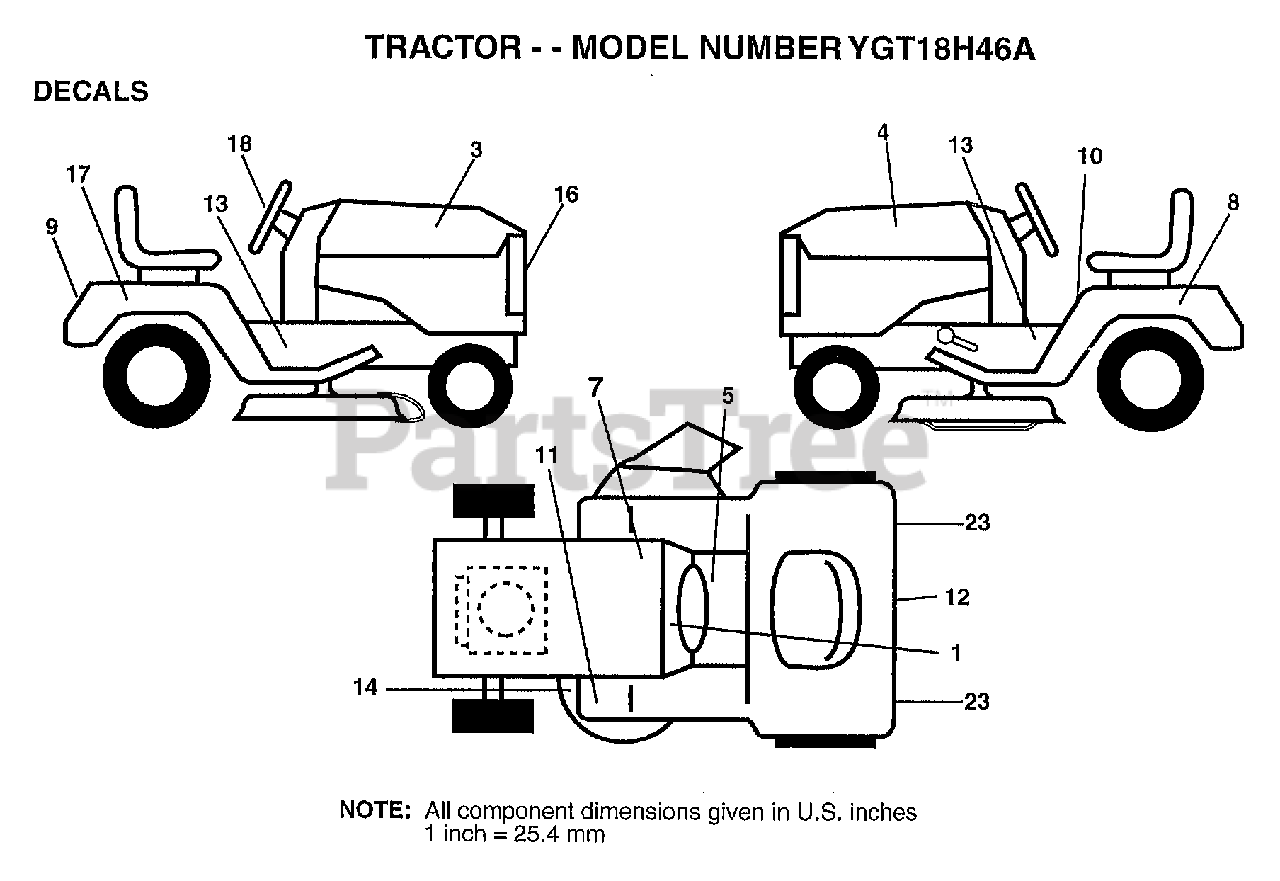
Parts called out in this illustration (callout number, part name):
1	"DECAL-INST,OPER"
3	"DECAL HOOD,RH,18H"
4	"DECAL-HOOD,LH,18H"
5	DECAL BRAK PARK
7	DECAL.BATRY.3-3908
8	DECAL FENDER LH
9	DECAL FENDER
10	"DECAL DANGER,FEND"
12	DECAL D-BAR CNTRL
13	"DECAL-CHASSIS,46"""
14	"DECAL.V.BELT.44"""
16	DECAL GRILLE
17	DECAL FENDER RH
18	DECAL INS STRG WH
23	REFLECTOR-TAIL YT
